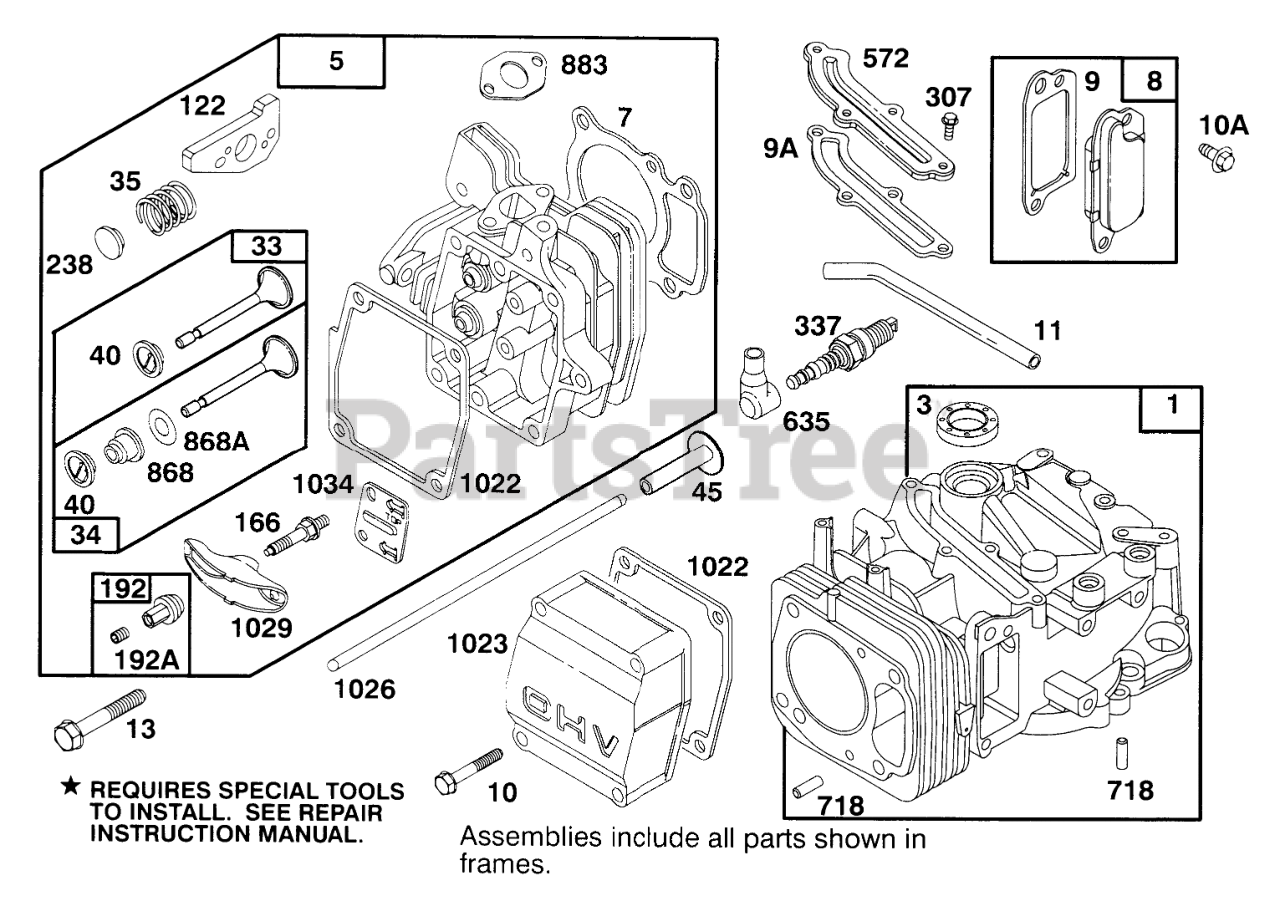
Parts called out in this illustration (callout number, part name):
1	CYLINDER ASSEMBLY
3	SEAL - OIL
5	CYLINDER HEAD
7	CYLINDER HEAD GASKET
8	BREATHER ASM
9	BREATHER GASKET
9A	GASKET-BREATHER
10	HEX HEAD SCREW
10A	HEX HEAD SCREW
11	TUBE - BREATHER
13	CYLINDER HEAD SCREW
33	EXHAUST VALVE
34	INTAKE VALVE
35	VALVE SPRING
40	SPRING RETAINER
45	VALVE TAPPET
122	ADAPTER ASSEMBLY
166	ROCKER ARM STUD
192	Ball & Screw-Rocker Arm (Incl. Ref. #192A)
192A	Screw-Set
238	VALVE CAP
307	SCREW - SEM
337	PLUG-SPARK
572	BAFFLE - CYCLINDER
635	SPARK PLUG ELBOW
718	DOWEL - SLEEVE
868	SealAssy-Valve
868A	Seal-Valve
883	EXHAUST GASKET
1022	ROCKER COVER GASKET
1023	COVER - VALVE
1026	PUSH ROD
1029	ROCKER ARM
1034	PUSH ROD GUIDE
